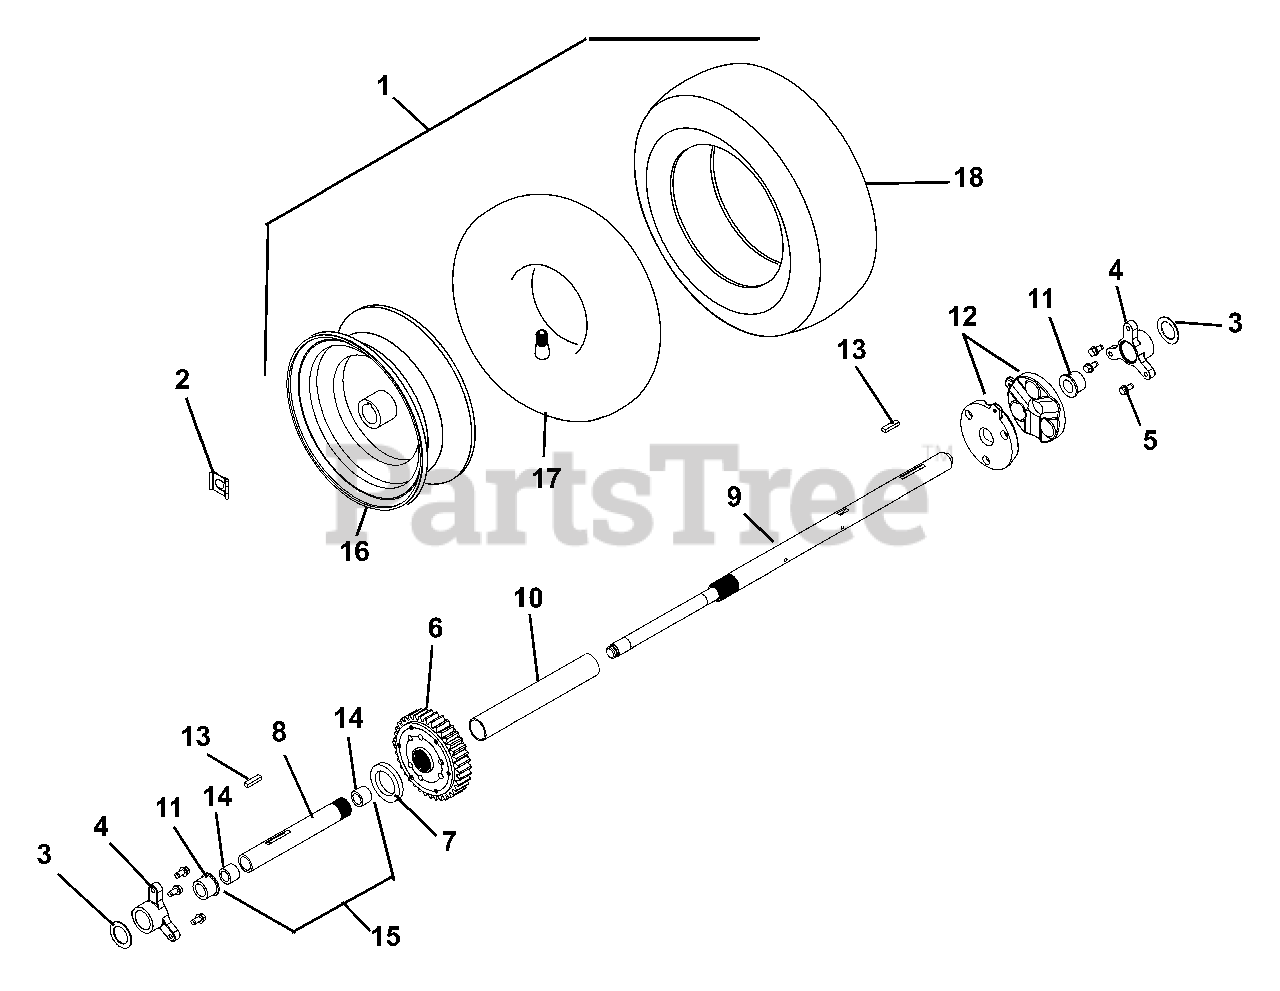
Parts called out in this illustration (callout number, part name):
1	Tire/Wheel Assembly RH 16 x 6.50 - 8 Differential
1	Tire/Wheel Assembly LH 16 x 6.50 - 8 Differential
2	Clip, Snap
3	Washer, Flat Steel 1.010 x 1.505 x .062
4	Bushing, Rake Shaft 1"
5	Screw, Tapping .25-20 x .50
6	Differential, Remote Assembly
7	Washer, Flat Nylon 1.38 x 2.00 x .25
8	Axle, Differential-Short
9	Axle, Differential-Long
10	Tube, Axle
11	Bushing, Flange Split Nyliner 1.0" HP
12	Cam, Differential
13	Key .25 x .188 x 1.00
14	Bushing, Sleeve .706 x .764 x .75
15	Axle, Differential with Bushings
16	Hub, Wheel- 16 x 6.5-8 Differential
17	Tube 16 x 6.50- 8
18	Tire, X-TRAC 16 x 6.5-8
